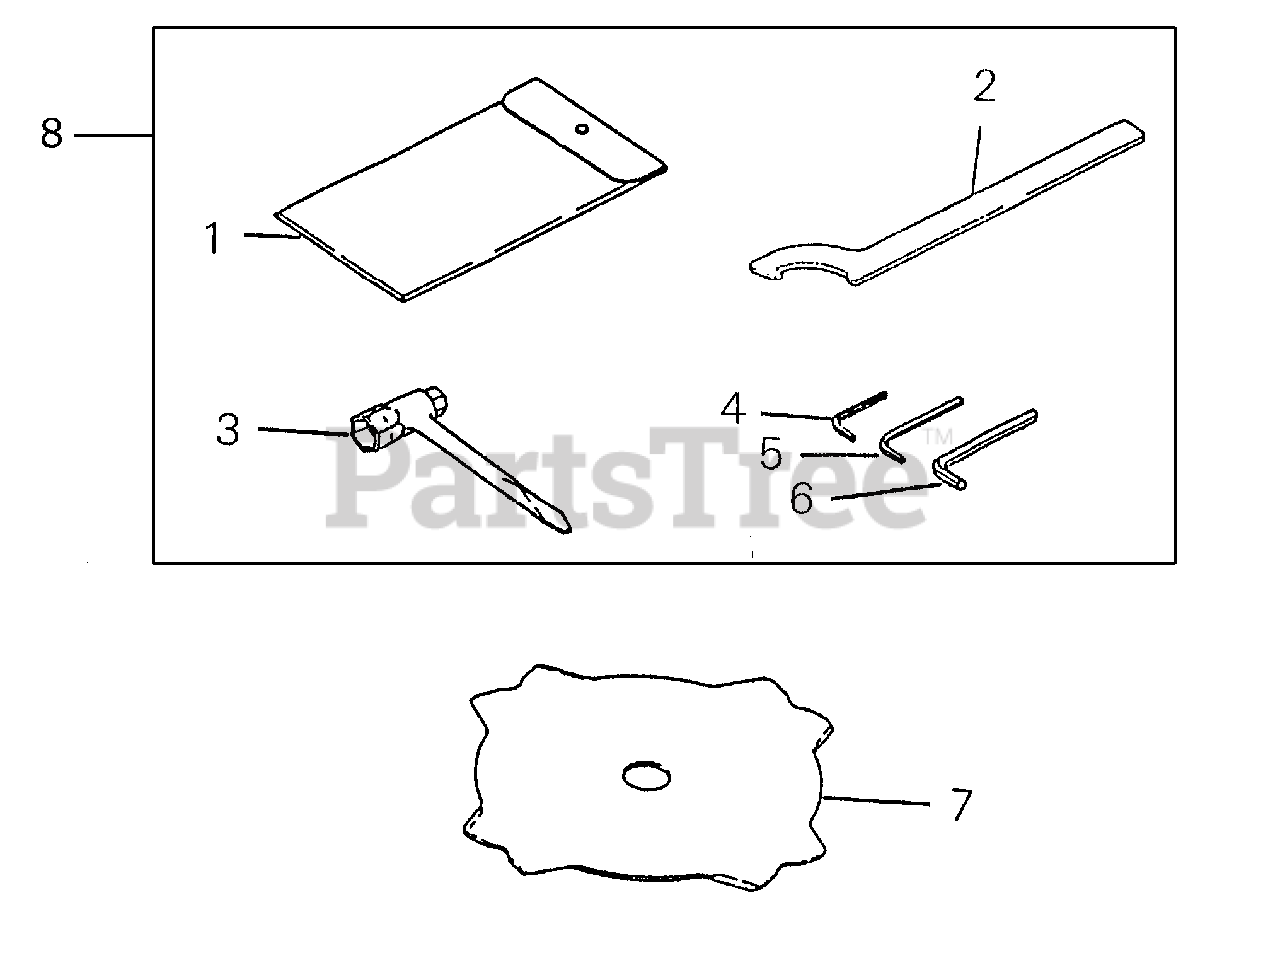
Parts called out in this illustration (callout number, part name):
1	BAG, TOOL
2	HOOK, SPANNER
3	T-WRENCH 13×19 MM
4	WRENCH, ALLEN 3 MM
5	WRENCH, ALLEN 4 MM
6	WRENCH, ALLEN 5 MM
7	BLADE, 10" 80-TOOTH
8	TOOL KIT, SERVICE
